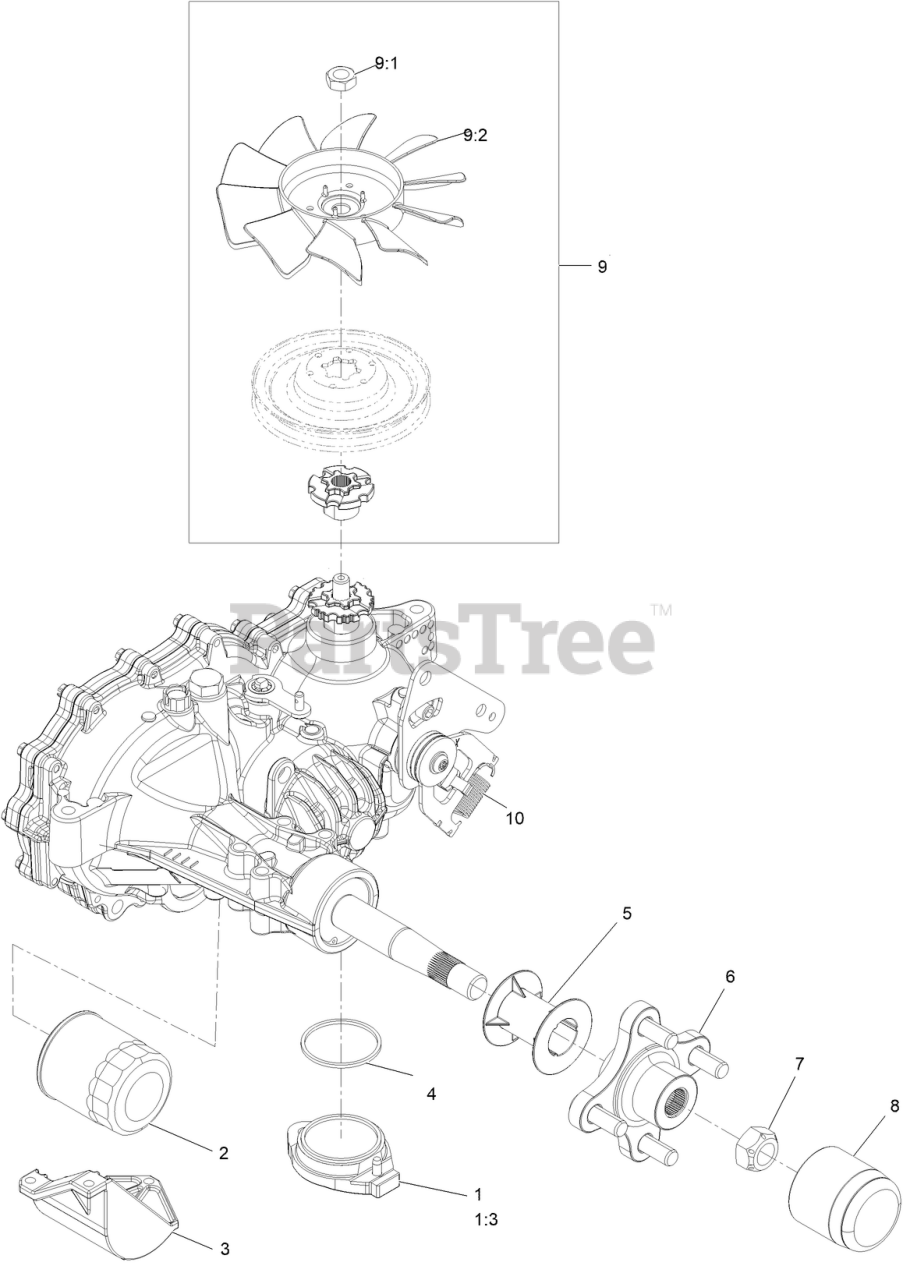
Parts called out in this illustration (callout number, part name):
1	CHARGE KIT
1:3	O RING-SEAL
2	ELEMENT-OIL FILTER, HYD
3	GUARD-FILTER, RH
4	O RING-SEAL
5	TUBE-AXLE
6	HUB-OFFSET
7	NUT-HUB
8	CAP-AXLE, LONG
9	Fan And Pulley Kit
10	SPRING-EXTENSION
